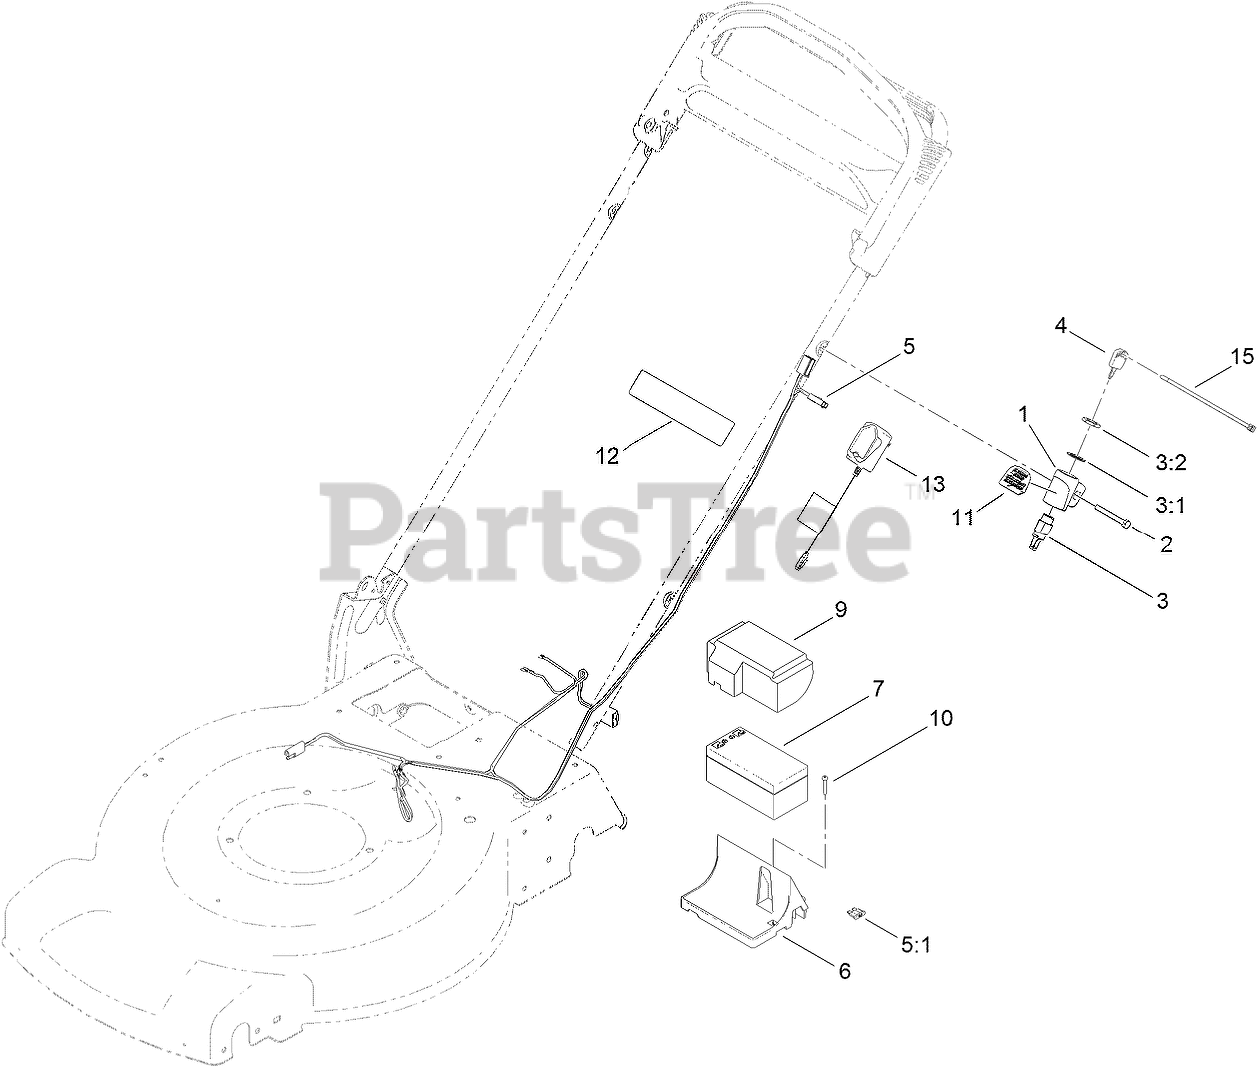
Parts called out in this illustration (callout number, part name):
1	MOUNT-SWITCH
2	SCREW-HANDLE
3	STARTER SWITCH ASM
3:1	WASHER-TOOTH, INTERNAL
3:2	NUT-HH
5	HARNESS-WIRE
5:1	FUSE-40 AMP
6	TRAY-BATTERY
7	BATTERY-WET
9	COVER-BATTERY
10	SCREW-PPH, PLASTITE
11	DECAL-ELECTRIC START
12	DECAL-WARNING
13	CHARGER-BATTERY
15	TIE-CABLE
